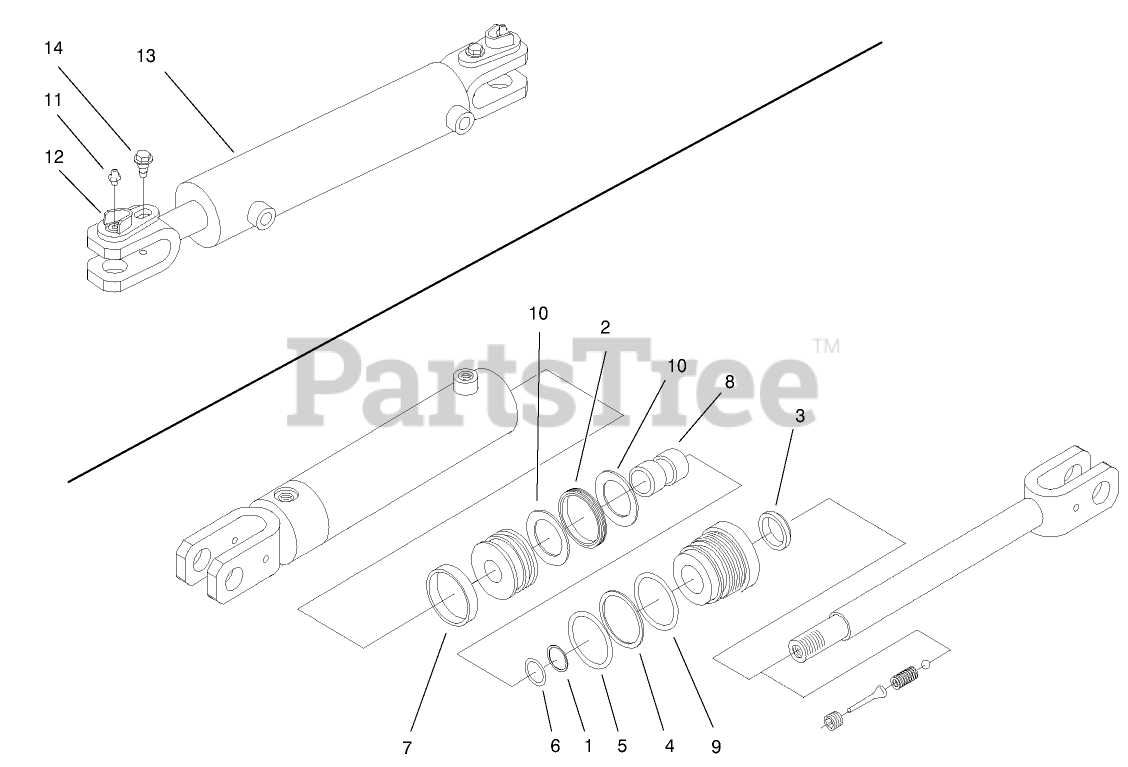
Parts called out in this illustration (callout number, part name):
2	PSP Seal
3	Rod-Wiper
6	Polypak
7	Ring-WEAR
8	Ring-WEAR
11	FITTING-GREASE
12	PIN-PIVOT
13	Cylinder-Hydraulic
14	BOLT-SHOULDER
